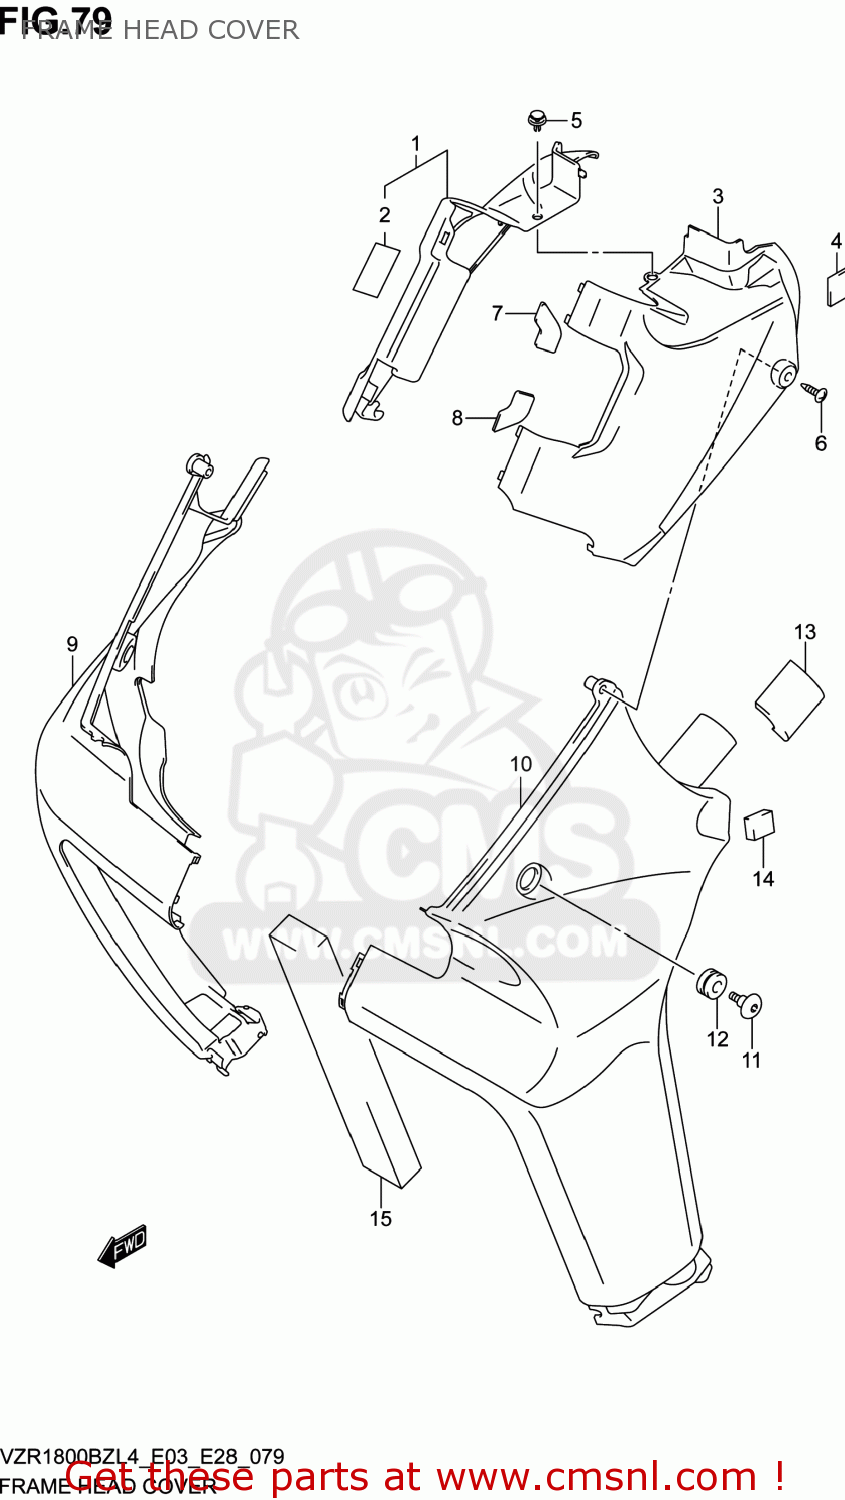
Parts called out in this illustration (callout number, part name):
1	COVER,FRAME HEAD,R(BLACK)
2	PROTECTOR
3	COVER,FRAME HEAD,L(BLACK)
4	CUSHION,RADIATOR COVER INNER
5	CLIP
6	SCREW
7	TAPE,HEAD COVER UPR
8	TAPE,HEAD COVER LWR
9	COVER,FRAME BODY UPR,R
10	COVER,FRAME BODY UPR,L
11	SCREW(6X20)
12	CUSHION
13	CUSHION
14	CUSHION,RADIATOR COVER INNER
15	CUSHION,FRAME BODY COVER,R
